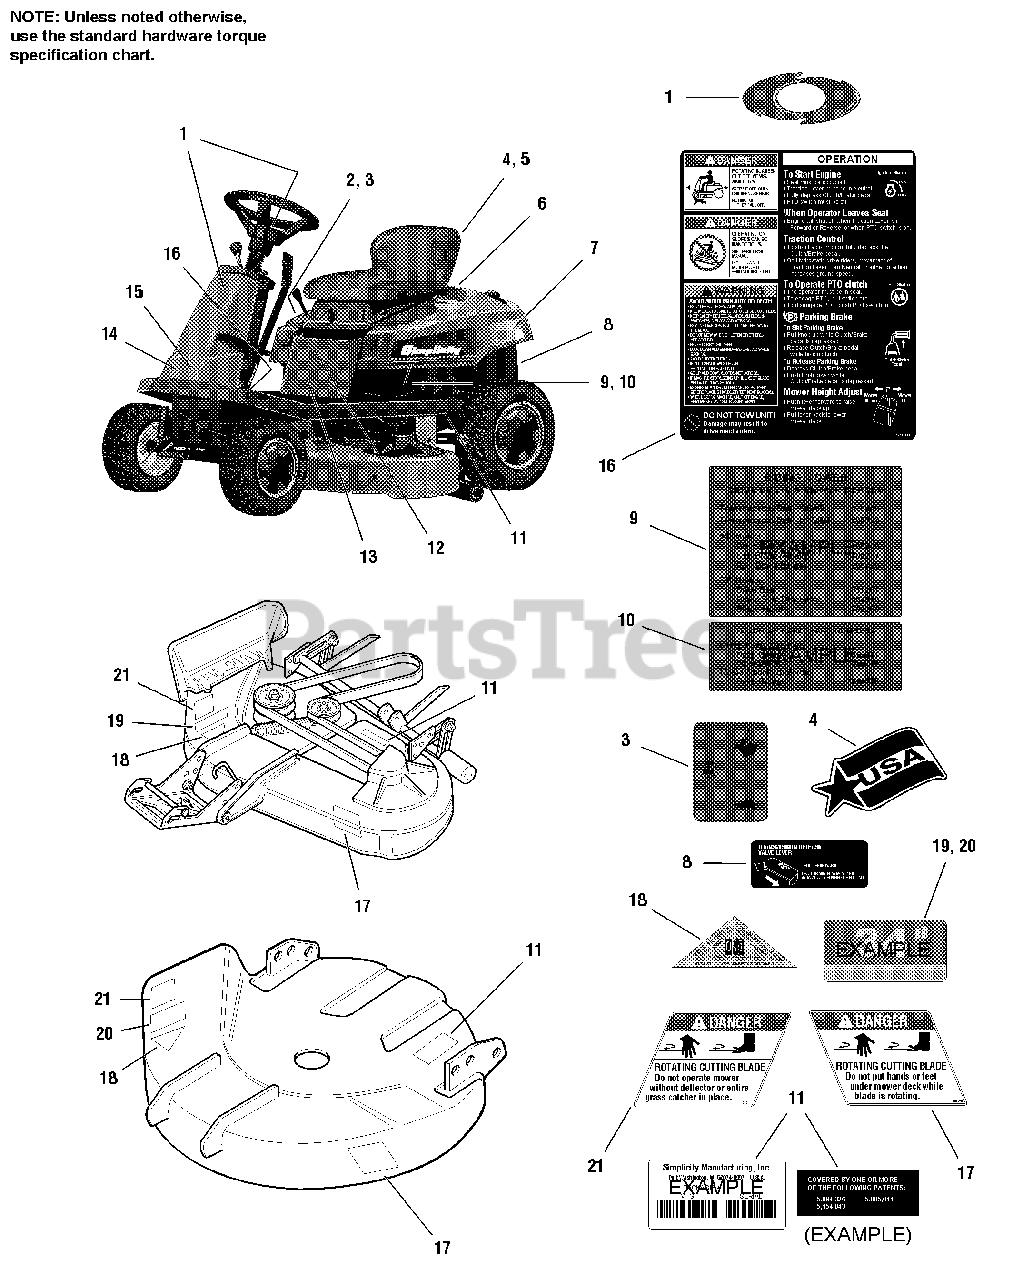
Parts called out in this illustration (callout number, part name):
1	DECAL, Icon (11G, 13H, 14H)
2	DECAL, Decibel, Export Only
3	DECAL,Throttle/Choke
4	DECAL, USA
5	DECAL, Logo, AGCO Allis
6	DECAL, Seat Deck Stripe, RH
7	DECAL, Seat Deck Stripe, LH
8	DECAL, Transmission Release
9	DECAL, Belt & Blade Replacement
10	DECAL, Touch-up Paint
11	I.D. PLATE
12	DECAL, "CORONET"
13	DECAL, Model, Coronet, 12 - 5 Speed
13	DECAL, Model, Coronet, 12 - Hydro
13	DECAL, Model, Coronet, 13 - Hydro
13	DECAL, Model, Coronet, 11 - 5 Speed
13	DECAL, Model, Coronet, 14 - Hydro
14	DECAL, CE
15	DECAL, Power Mass
16	DECAL, Operating Instructions
17	DECAL, Danger, Rotating Cutting Blade
18	DECAL, OPEI
19	DECAL, Cutting Width - 34"
20	DECAL, Cutting Width - 30"
21	DECAL, Danger, Chute In Place
